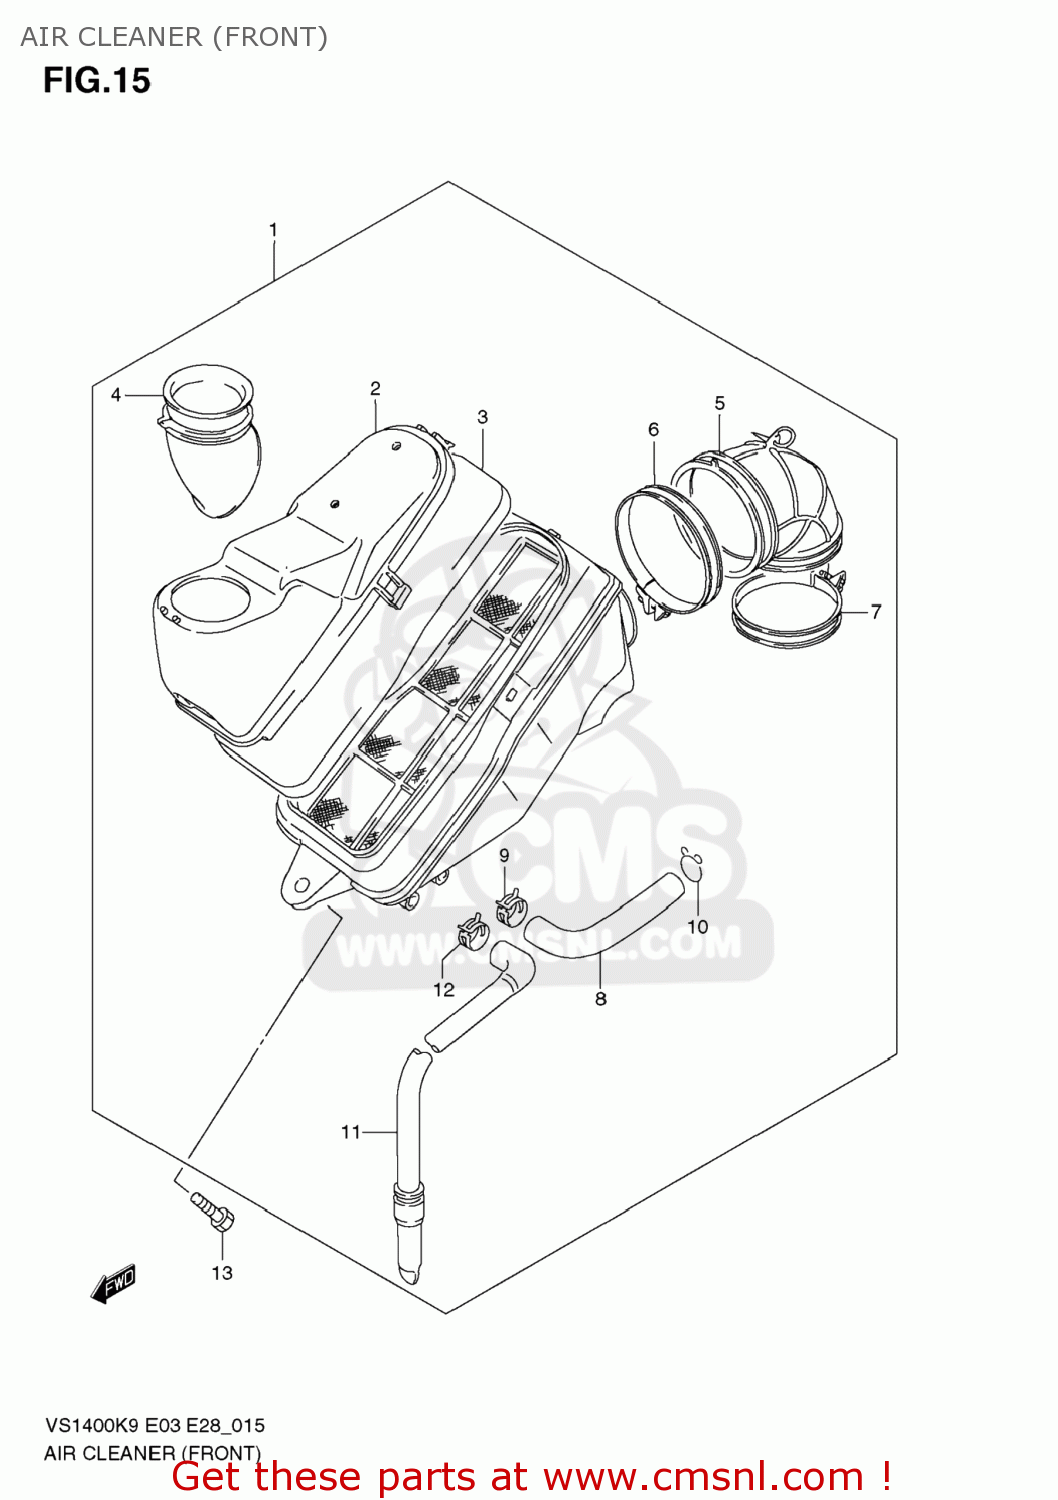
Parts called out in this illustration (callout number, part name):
1	CLEANER ASSY,AIR FR
2	CAP,AIR CLEANER FR
3	FILTER,AIR FR
4	TUBE,INLET
5	TUBE,AIR CLEANER OUTLET
6	CLAMP
7	CLAMP
8	TUBE,BREATHER
9	CLIP
10	CLIP
11	TUBE,DRAIN
12	CLIP
13	BOLT
